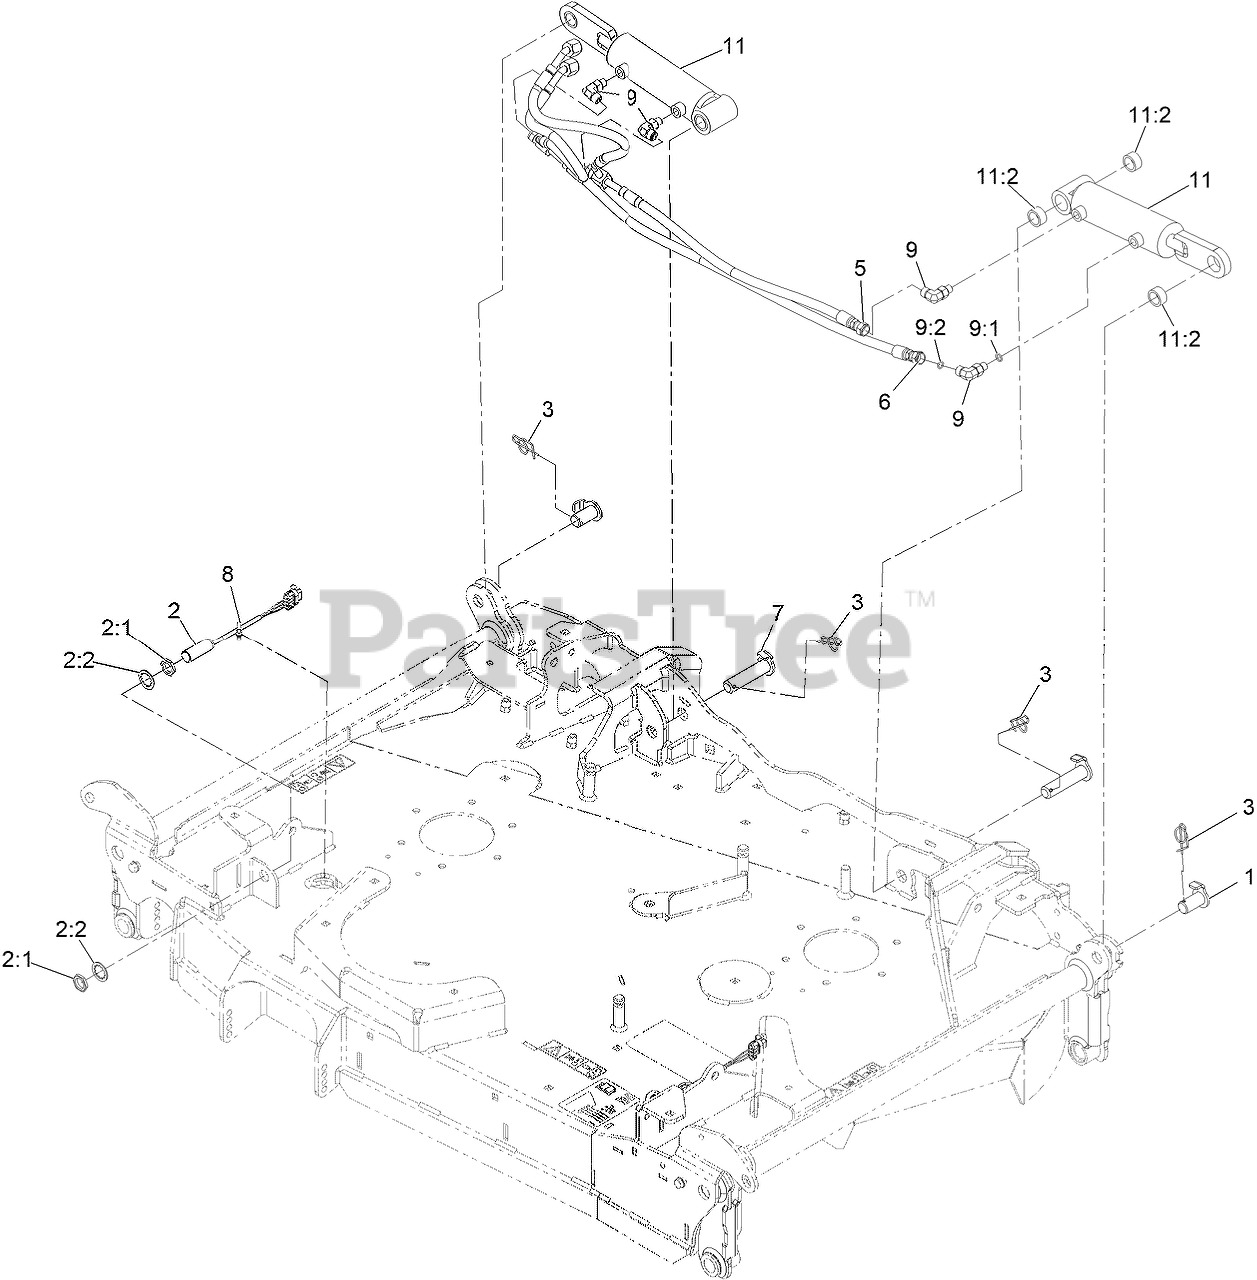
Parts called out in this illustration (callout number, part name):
1	PIN-CYLINDER
2	PROXIMITY SWITCH ASM
2:1	NUT-HEX
2:2	WASHER-LOCK, INTERNAL TOO
3	PIN-LOCKING COTTER
5	HOSE ASM
6	HOSE ASM
7	ASM-CYL PIN BASE
8	TIE-CABLE
9	FITTING-ELBOW, 90 DEG
9:1	O-RING
9:2	O-RING
11	CYL-Deck Fold
11:2	BUSHING-0.75X1.00X0.50 LONG
